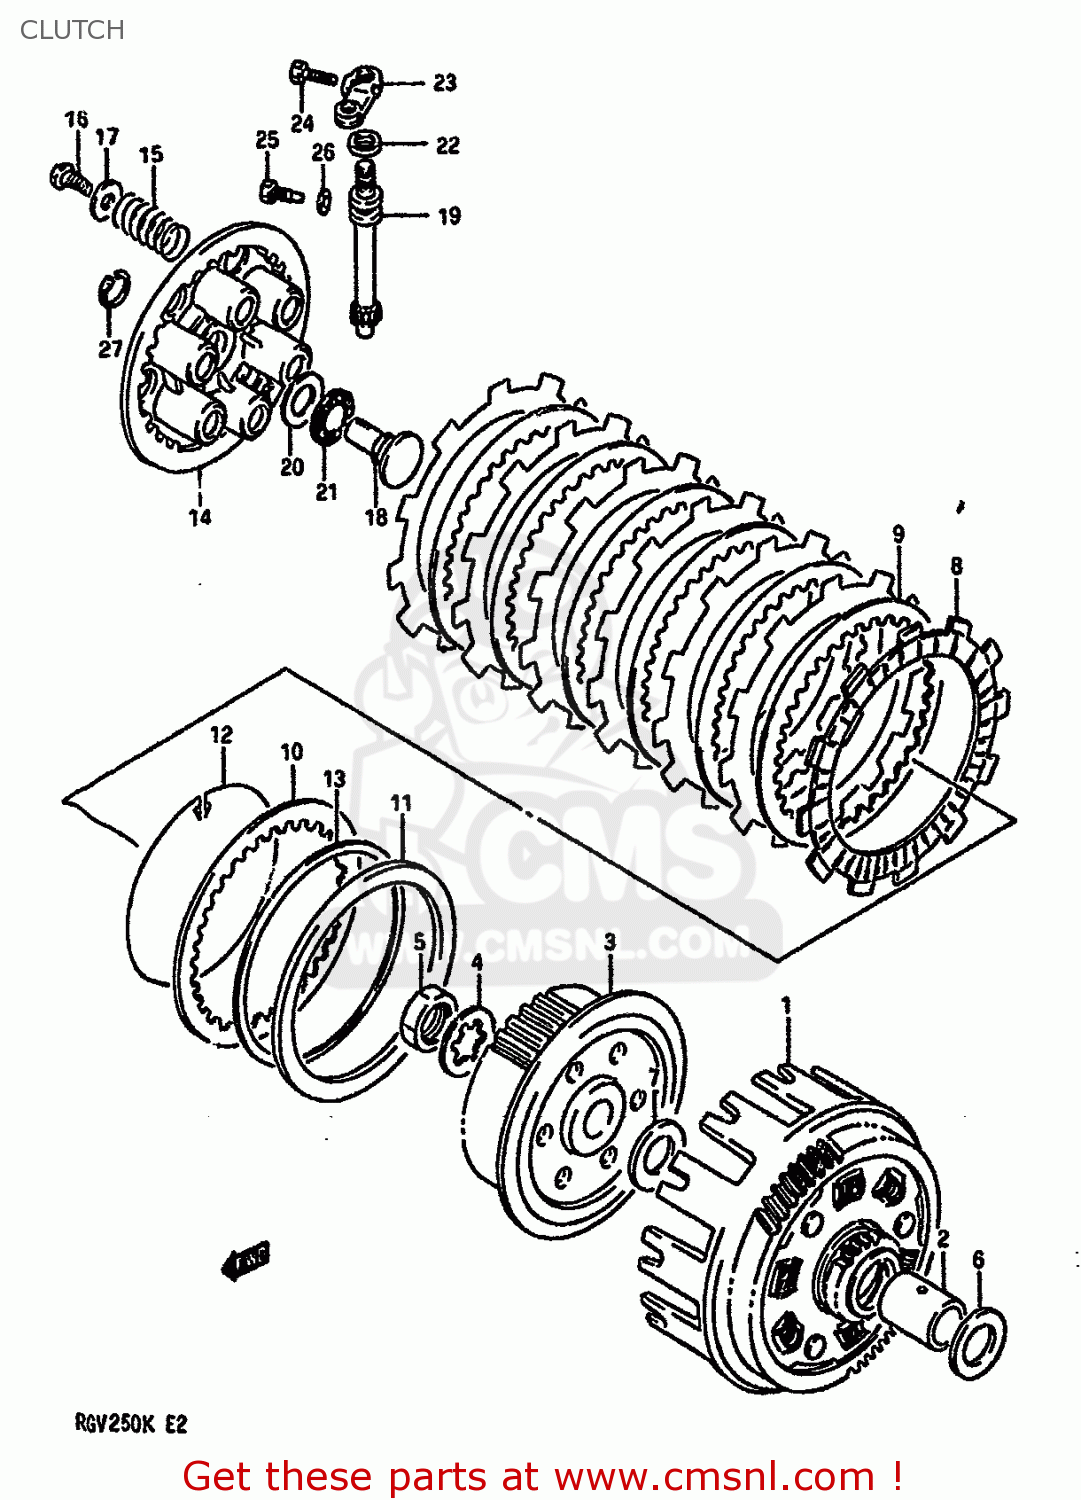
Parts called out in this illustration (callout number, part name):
1	GEAR ASSY,PRIMARY DRIVEN
2	SPACER,PRIMARY DRIVEN
3	HUB,CLUTCH SLE
4	WASHER,LOCK
5	NUT (20MM)
6	WASHER(20X36X3)
7	WASHER(20X36X2)
8	PLATE,CLUTCH
9	PLATE,CLUTCH DRIVEN (NAS)
10	PLATE,CLUTCH DRIVEN(T:2.0) (NAS)
11	SEAT,WAVE WASHER
12	RING,STOPPER
13	WASHER
14	DISC,CLUTCH PRESSURE
15	SPRING
16	BOLT
17	WASHER
18	RACK,CLUTCH RELEASE
19	PINION,CLUTCH RELEASE
20	WASHER
21	BEARING(15X28X2)
22	SEAL,OIL(10X17X5)
23	ARM,CLUTCH RELEASE
24	BOLT
25	BOLT(6X12)
26	WASHER
27	RING,SNAP
